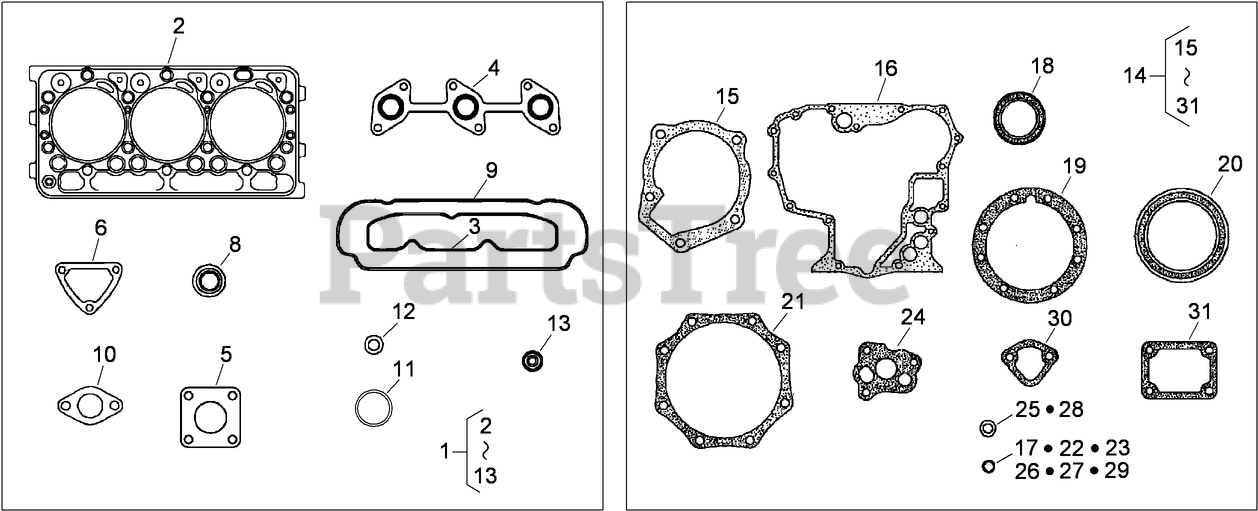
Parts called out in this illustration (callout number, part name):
1	UPPER GASKET KIT
2	GASKET-HEAD, CYLINDER
3	GASKET-MANIFOLD, INTAKE
4	GASKET-MANIFOLD, EXHAUST
5	GASKET-MUFFLER
6	GASKET-FLANGE, WATER
8	SEAL-STEM, VALVE
9	GASKET-COVER, HEAD
10	GASKET-THERMOSTAT
11	O-RING
12	GASKET
13	SEAL-HEAT
14	LOWER GASKET KIT
15	GASKET-PUMP, WATER
16	GASKET-CASE, GEAR
17	O-RING
18	SEAL-OIL
19	GASKET-CASE, BEARING
20	SEAL-OIL
21	GASKET-COVER, CASE
22	O-RING
23	O-RING
24	GASKET-PUMP, OIL
25	GASKET
26	O-RING
27	O-RING
28	GASKET-PAN, OIL
29	O-RING
30	GASKET-PUMP, FUEL
31	GASKET-PLATE, CONTROL
